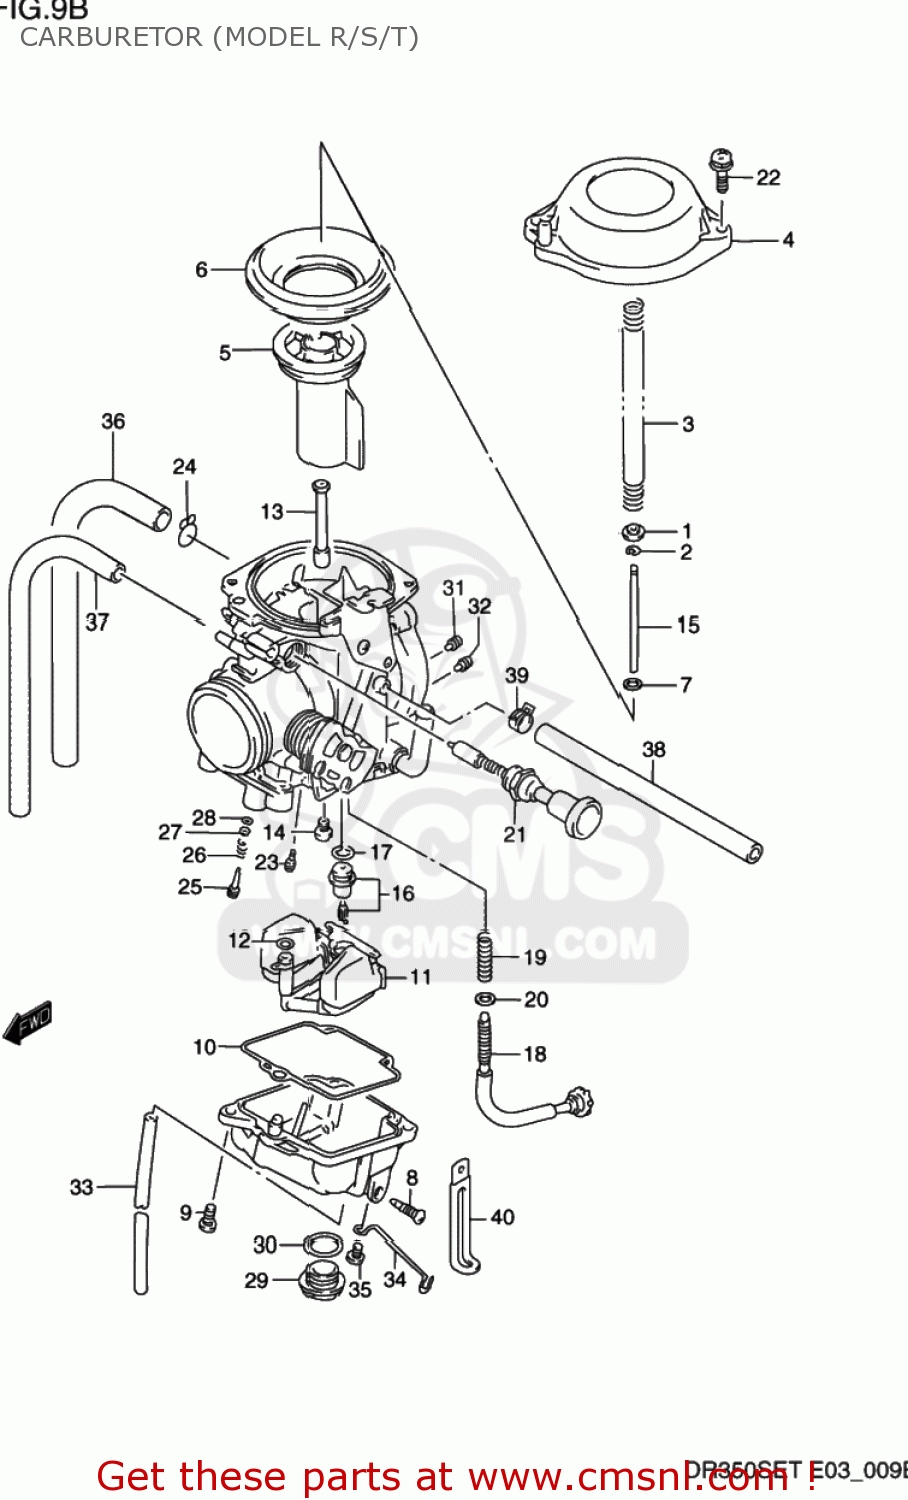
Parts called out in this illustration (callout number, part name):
1	RING
2	E RING
3	SPRING
4	COVER,DIAPHRAGM
5	VALVE PISTON
6	DIAPHRAGM
7	RING
8	SCREW,DRAIN
9	SCREW
10	GASKET,FLOAT CHAMBER (NAS)
11	FLOAT ASSY
12	O RING
13	JET,NEEDLE (O-6)
14	JET,MAIN(127.5)
15	NEEDLE,JET
16	VALVE ASSEMBLY,NEEDLE
17	O-RING,NEEDLE VALVE
18	ADJUSTER
19	SPRING,THROTTLE SCREW
20	WASHER,STARTER SHAFT
21	PLUNGER ASSEMBLY
22	SCREW
23	JET,PILOT(37.5)
24	CLIP
25	SCREW,PILOT
26	SPRING
27	WASHER
28	O RING,PILOT AIR SCREW
29	SCREW,GUIDE
30	O RING,DRAIN PLUG
31	JET,AIR(1.3)
32	JET,AIR(0.6)
33	HOSE(3X5X600)
34	CLIP
35	SCREW
36	HOSE(7X11X600)
37	HOSE (4.5X8.5X600)
38	HOSE
39	CLIP
40	CLAMP
